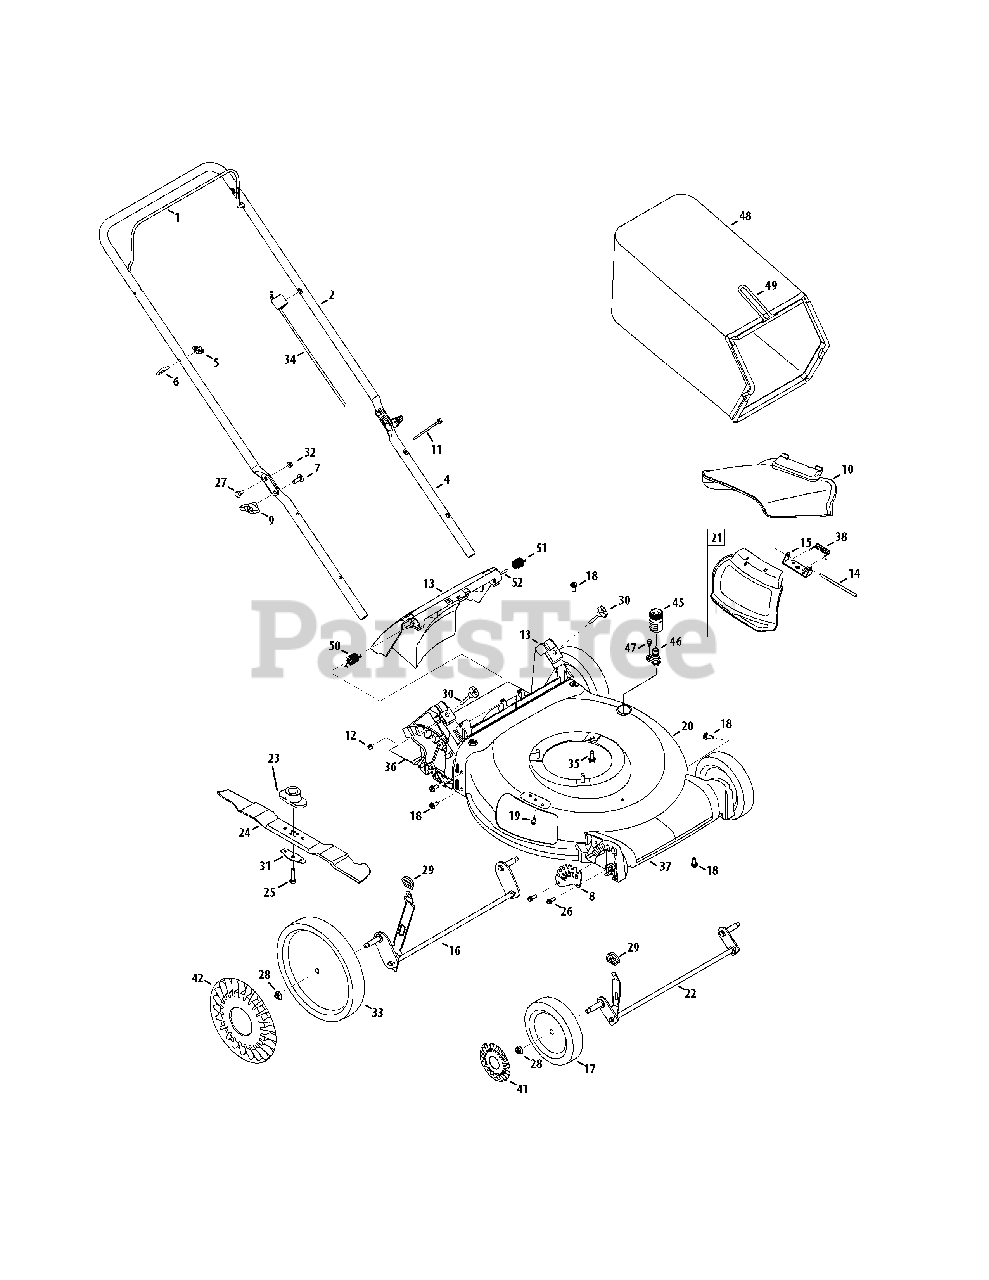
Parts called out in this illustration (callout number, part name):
1	Blade Control Handle - Black
2	Upper Handle - Black (adjustable)
4	Lower Handle
5	Knob 1/4-20
6	Rope Guide Bolt
7	Carriage Bolt 5/16-18
8	Front Height Adjustment Plate
9	Wing Knob 5/16-18 Black
10	Chute Deflector (w/clip)
11	Cable Tie
12	Sq. Nut 1/4-20
13	Rear Baffle
14	Hinge Pin
15	Chute Deflector Bracket
16	Rear Axle Ass’y - 8" wheel
17	Wheel Ass’y 7 x 2.0 Sleeve Zag Black
18	Hex Hd. Cap Scr. 5/16-14 x .75
19	Sems TT Scr. 1/4-20 x .50
20	21" Deck Ass’y (3 in 1 w/washout nozzle)
21	Hinged Mulch Plug Ass’y (Incl. ref. no.15, 38 & 14)
22	Front Axle Ass’y - 7 " wheel
23	Blade Adapter (25 mm x 1.19)
24	21" Mulching Blade
25	Hex Bolt 3/8-24 x 1.5" Lg. (Gr 8)
26	Screw, 1/4-15 x .750
27	Shoulder Screw .375 x .126 x 1/4-20
28	Flange Locknut 3/8-16 Gr. F Nylon
29	Knob (Black)
30	Knob 1/4-20 x 1.73 Black
31	Blade Bell Support
32	Flanged Lock Nut 1/4-20 Gr. F Nylon
33	Wheel Ass’y 11 x 2 SL: Zag Black
34	Control Cable, 125 cc B&S
35	Hex Wash HD Tap Scr 3/8-16 x 1.0
36	Trailing Shield 4.54 x 17.37
37	Front Axle Cover
38	Torsion Spring
41	Hub Cap (8")
42	Hub Cap (11")
45	Water Nozzle Adapter
46	Deck Water Nozzle
47	Shoulder Screw 1/4-20 x .50
48	Grassbag, Black Dust Blocking
49	Grassbag Frame
50	Torsion Spring RH
51	Torsion Spring LH
52	Pivot Rod
